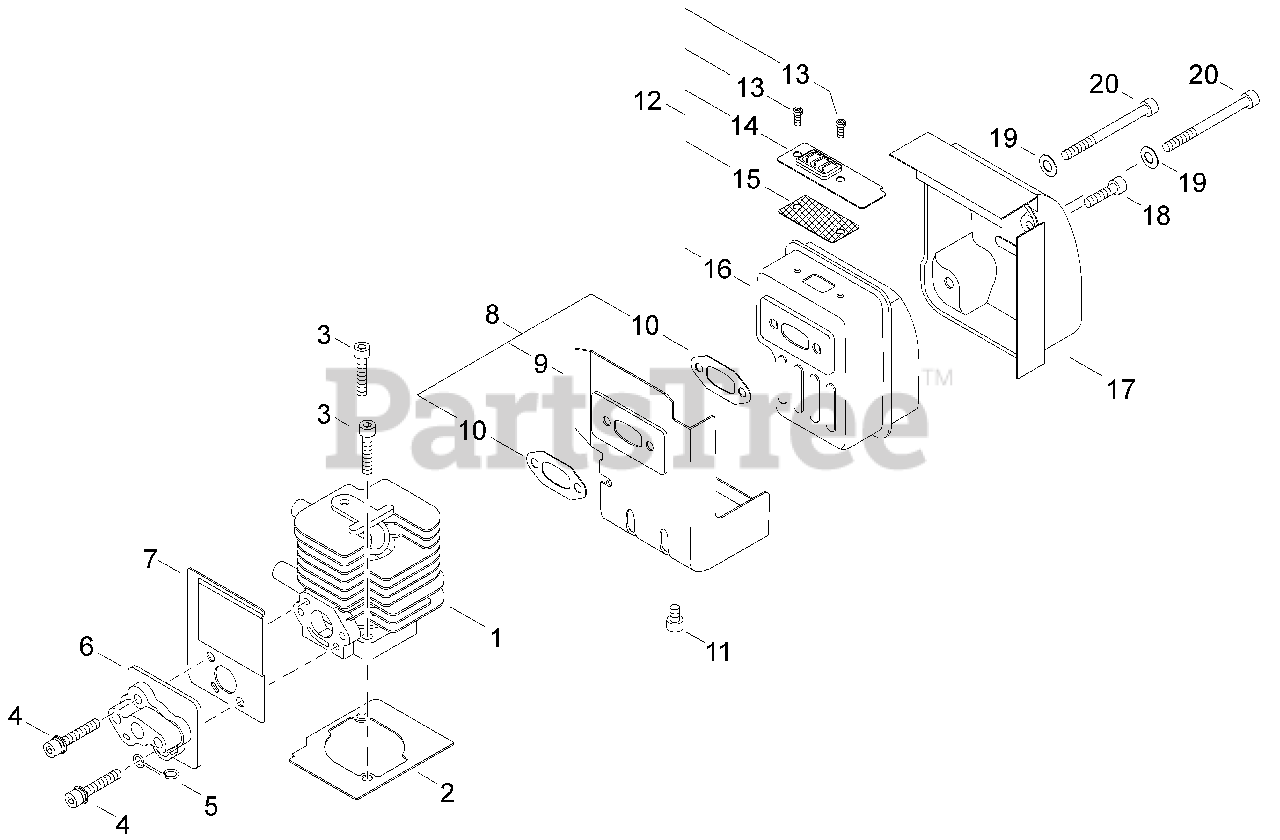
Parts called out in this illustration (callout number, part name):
1	CYLINDER
2	GASKET, CYLINDER
3	BOLT 5×25
4	BOLT SS M5×30
5	CLIP, VENT ASSY
6	INSULATOR, INTAKE
7	HEAT SHIELD, INTAKE
8	DEFLECTOR ASSY, EXHAUST HEAT
9	HEAT SHIELD, EXHAUST
10	GASKET, EXHAUST
11	BOLT 5×8
12	MUFFLER ASSY
13	SCREW M4×6
14	OUTLET, EXHAUST
15	SCREEN, SPARK ARRESTER
16	MUFFLER
17	COVER, MUFFLER
18	BOLT 5×20
19	WASHER SS 5 MM
20	BOLT M5×60
